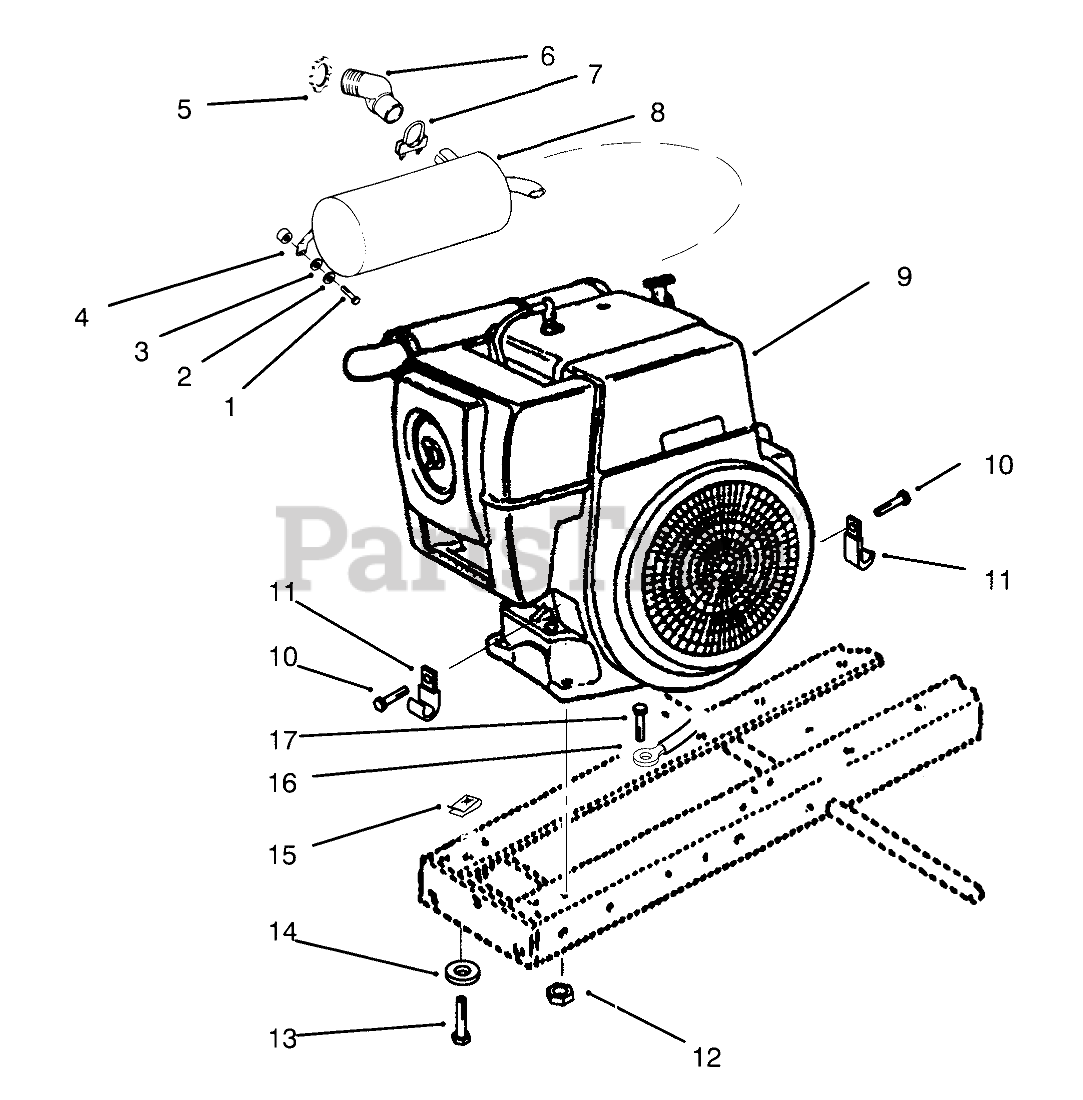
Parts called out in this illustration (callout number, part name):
1	SCREW-HH
2	WASHER-LOCK
3	WASHER-PLAIN
4	SPACER
5	Nut-Lock
6	Elbow
7	CLAMP-1 1/2
8	Muffler
9	Engine-12 Hp Kohler
10	Screw (Engine) Ref
11	CLIP
12	NUT-LOCK, NI
13	SCREW-HH
14	WASHER-LOCK
15	SPEED CLIP
16	WIRE GROUND
17	SCREW-HH
